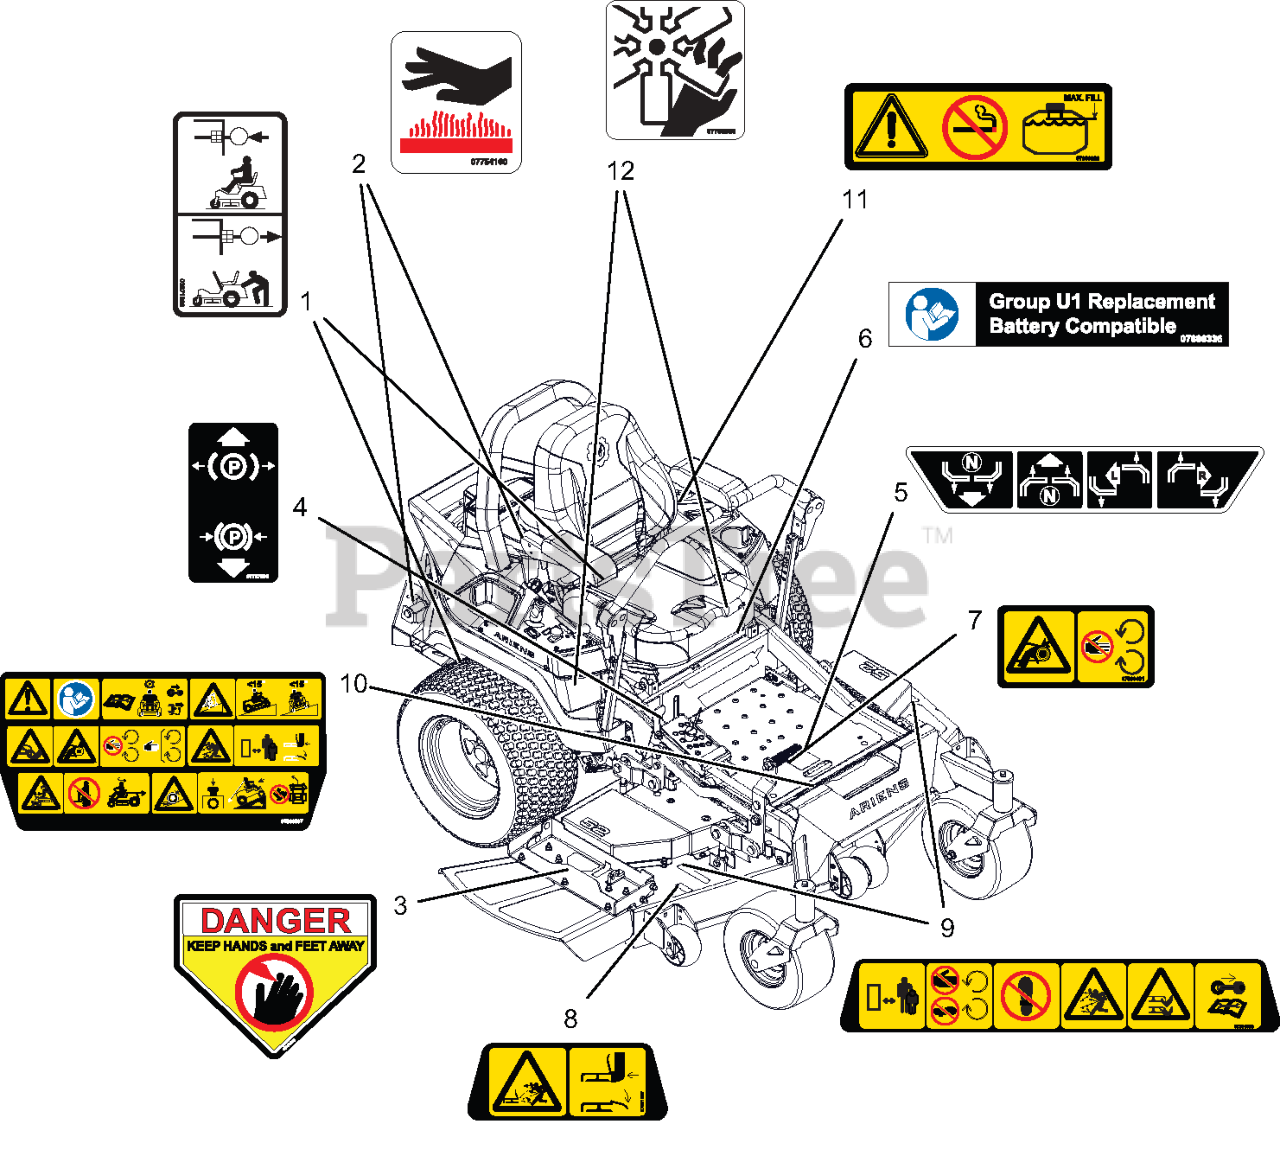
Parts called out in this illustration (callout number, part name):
1	DECAL, TRANSMISSION DISCONNECT
2	DECAL, HOT SURFACE
3	DECAL, DANGER
4	DECAL, PARKING BRAKE LEVER
5	DECAL, INSTRUCTIONAL-STEERING
6	DECAL, U1 BATTERY REPLACEMENT
7	DECAL, SAFETY - GUARDING
8	DECAL- SAFETY - DECK GUARDING
9	DECAL- SAFETY - MOWER DECK
10	DECAL, MAIN SAFETY
11	DECAL, FUEL WARNING
12	DECAL, DANGER FAN
